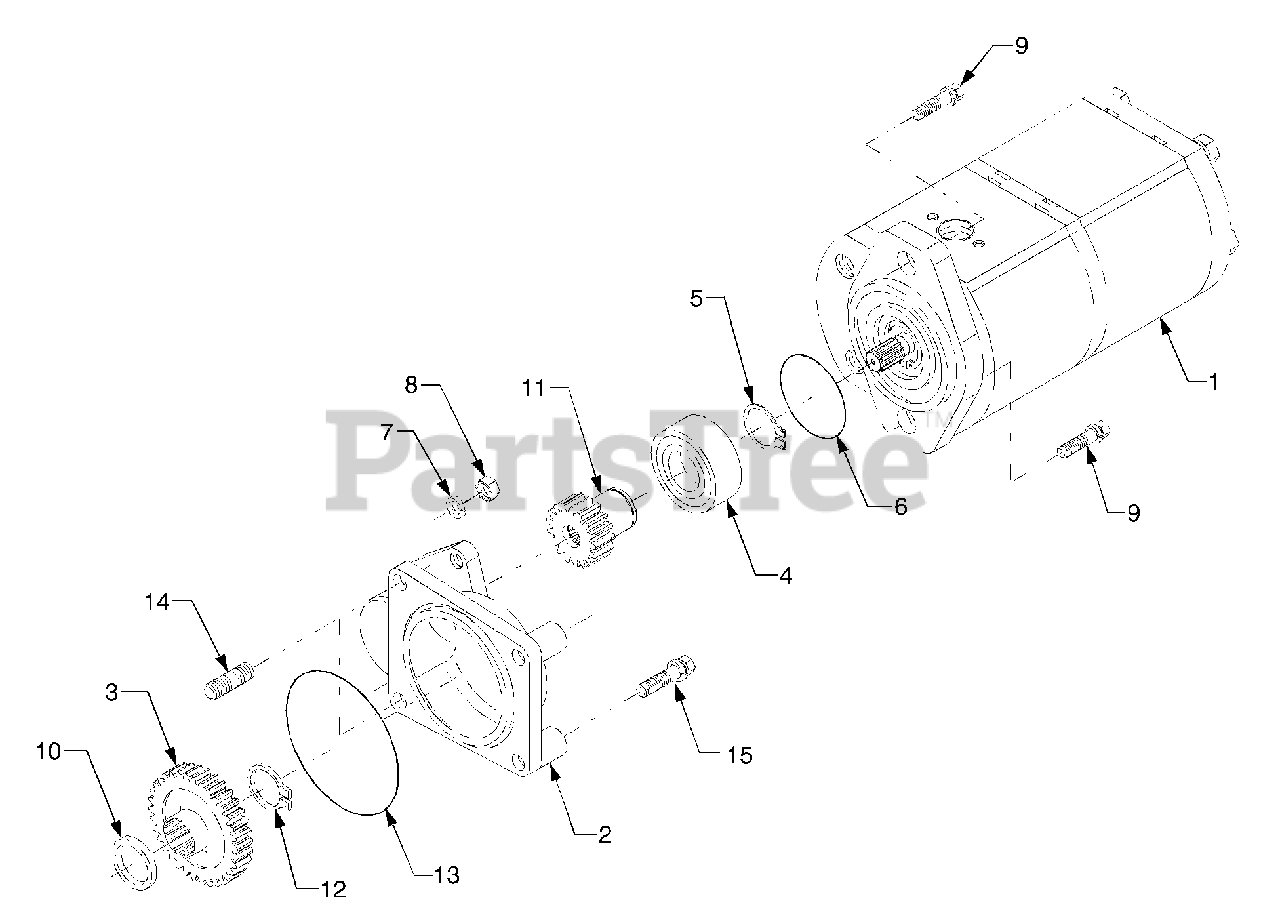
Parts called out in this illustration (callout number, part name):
1	Pump, Gear
2	Holder, Gear Pump
4	Bearing, Ball
5	Cir-clip, External
7	Washer, Spring
